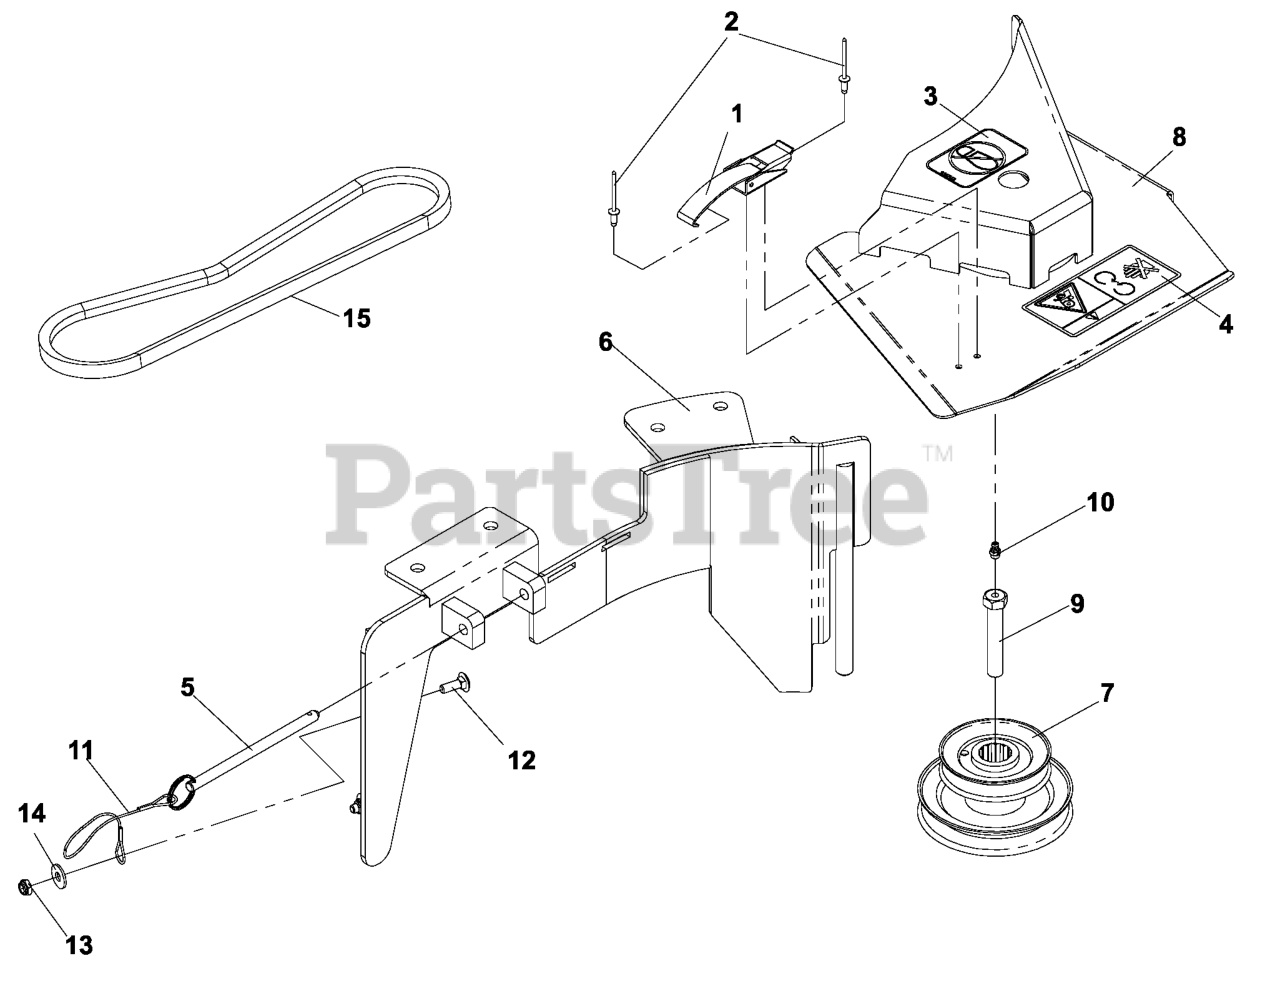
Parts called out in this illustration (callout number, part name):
1	DRAW LATCH
2	RIVET, BLIND, 5/32 DIA
3	DECAL, NO STEP
4	DECAL, BELT DRIVE
6	BLOWER DECK PLATE
7	42/48 LG DBL HEX STACK PULLEY
8	BELT SHIELD ASSY 48"
9	DRILLED BOLT 7/16-20 X 2 1/2"
10	ZERK
12	RHSNB 1/4C X 3/4
13	WASHER 1/4 FLAT
14	JAM NUT 1/4C (2 2 PW01)
